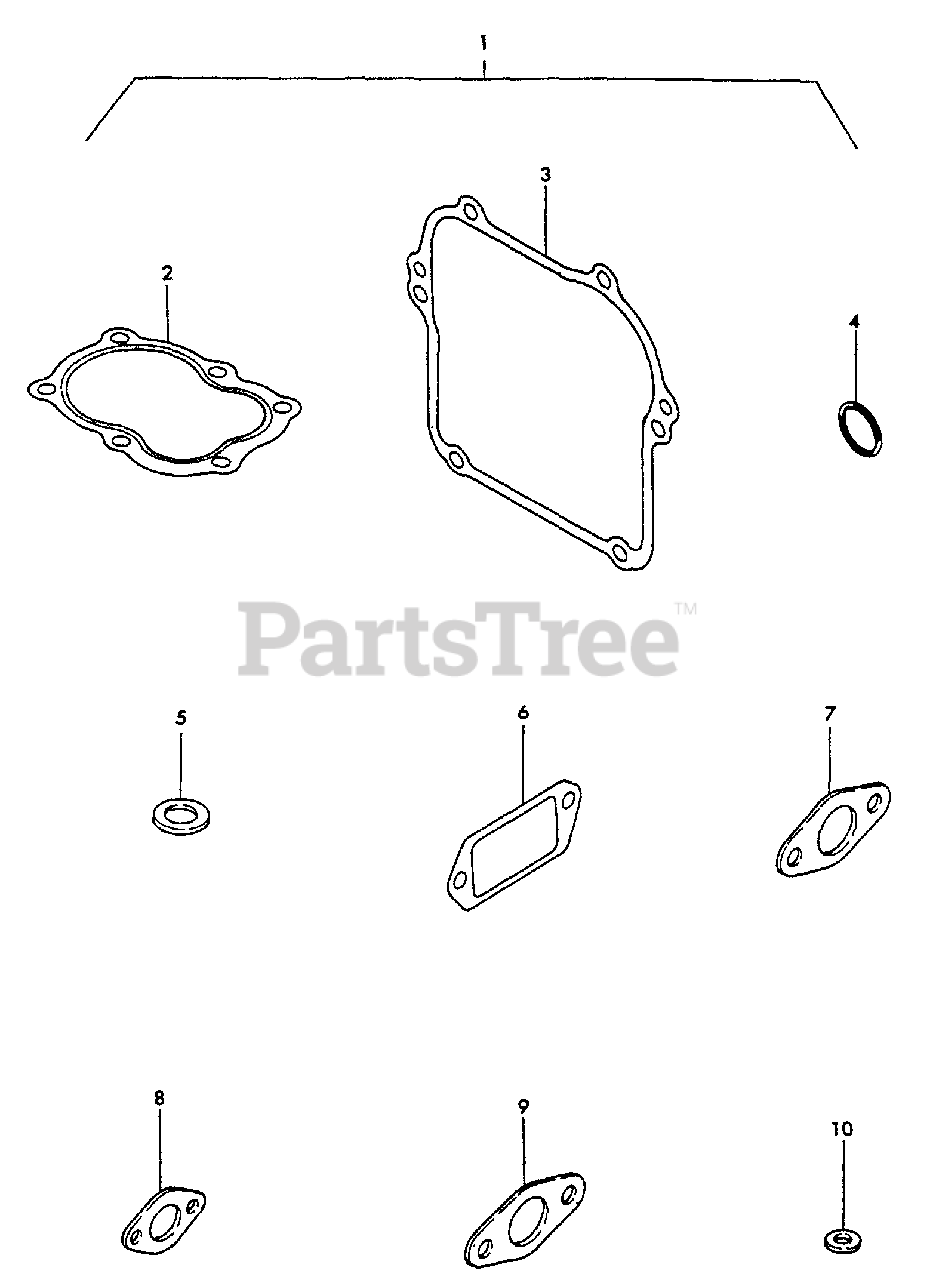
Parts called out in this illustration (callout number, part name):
1	GASKET KIT
2	GASKET, HEAD
3	GASKET, CRANKCASE
4	O-RING 1A P-15.0
5	GASKET
6	GASKET, BREATHER
7	GASKET
8	GASKET, EXHAUST
9	GASKET, INTAKE
10	NYLON PACKING -6
